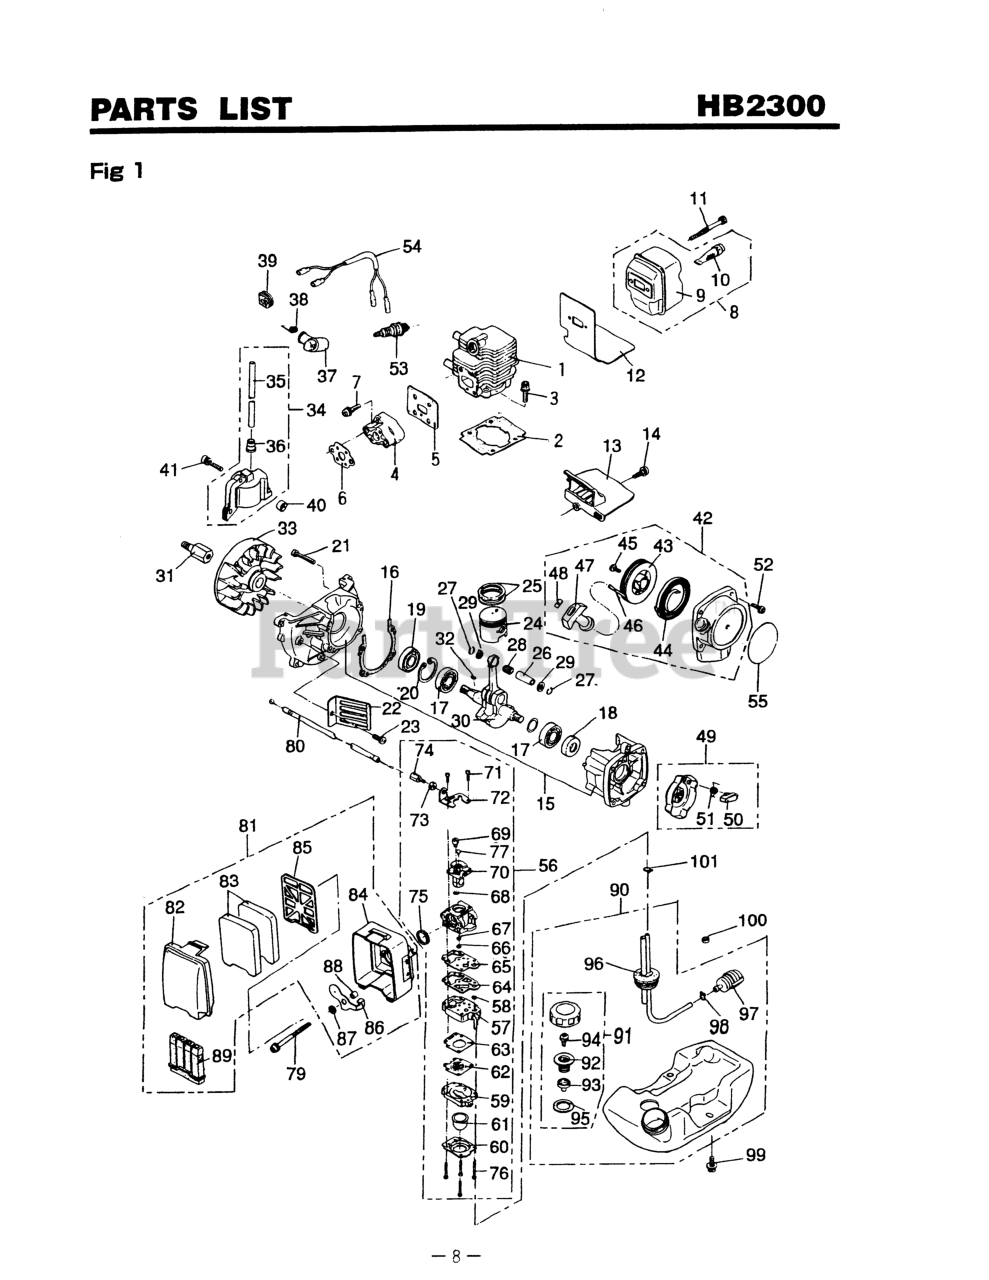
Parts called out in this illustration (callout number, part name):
1	CYLINDER
3	BOLT, M5 X 22
7	SCREW, M5X20 (RPLS.1400-75510)
10	ARRESTER (RPLS 5850-15140)
11	BOLT
12	GASKET
14	SCREW, M4 X 16
15	CRANKCASE
17	BEARING
18	SEAL, OIL (RPLS 1100-21210)
19	SEAL, OIL (RPLS 1140-21220)
20	RING, SNAP, M28 x 1.2
21	BOLT, M5 X 30
23	SCREW,M5 X 14 (RPLS 1400-15510
24	PISTON (REPLACES 1140-41110)
25	RING, PISTON (RPLS 1850-41210)
26	PIN, PISTON 5x8x26
27	RING, SNAP (RPLS 1101-41320)
29	WASHER
30	CRANKSHAFT (RPLS 1850-42000)
31	EXTENSION
32	KEY
35	CORD
36	CAP
38	SPRING
39	GROMMET
40	SPACER (RPLS -71260)
41	BOLT
42	RECOIL ASSEMBLY
43	REEL
44	SPRING, SPIRAL
45	SCREW (RPLS -75150)
47	KNOB
48	PLATE, STOPPER
49	PULLEY ASSY (RPLS -75210)
50	RATCHET (RPLS 1850-75220)
51	SPRING, RETURN
52	SCREW, M4 X 16
54	CORD COMPLETE
55	LABEL (USE -75611)
56	CARBURETOR
57	BODY, PUMP
59	BODY, PURGE
60	COVER, PUMP
61	PUMP, PRIMING
62	DIAPHRAGM (USE 4810-81260)
63	GASKET, DIAPHRAGM
64	DIAPHRAGM
65	GASKET, PUMP
66	JET
67	RING, O
68	RING
69	SWIVEL
70	VALVE ASSEMBLY
71	SCREW
73	NUT, CABLE ADJUSTER
74	SCREW, CABLE ADJUSTER
75	RING, PACKING
76	SCREW
77	WASHER
79	SCREW, M5 x 60
80	CABLE COMP (RPLS, -83100)
82	COVER
83	FILTER
84	HOUSING
85	PLATE
86	VALVE, CHOKE
87	WASHER
88	SLEEVE (REPLACES 1750-82060)
89	SILENCER
93	HOLDER, CAP
94	VALVE (NLA WHEN OUT)
95	PACKING
96	PIPE COMP.
97	FILTER (RPLS 1850-85300)
98	CLIP (REPLACES 2841-31280)
99	SCREW (REPLACES 4500-13180)
100	COLLAR (REPLACES -85530)
101	CLIP
